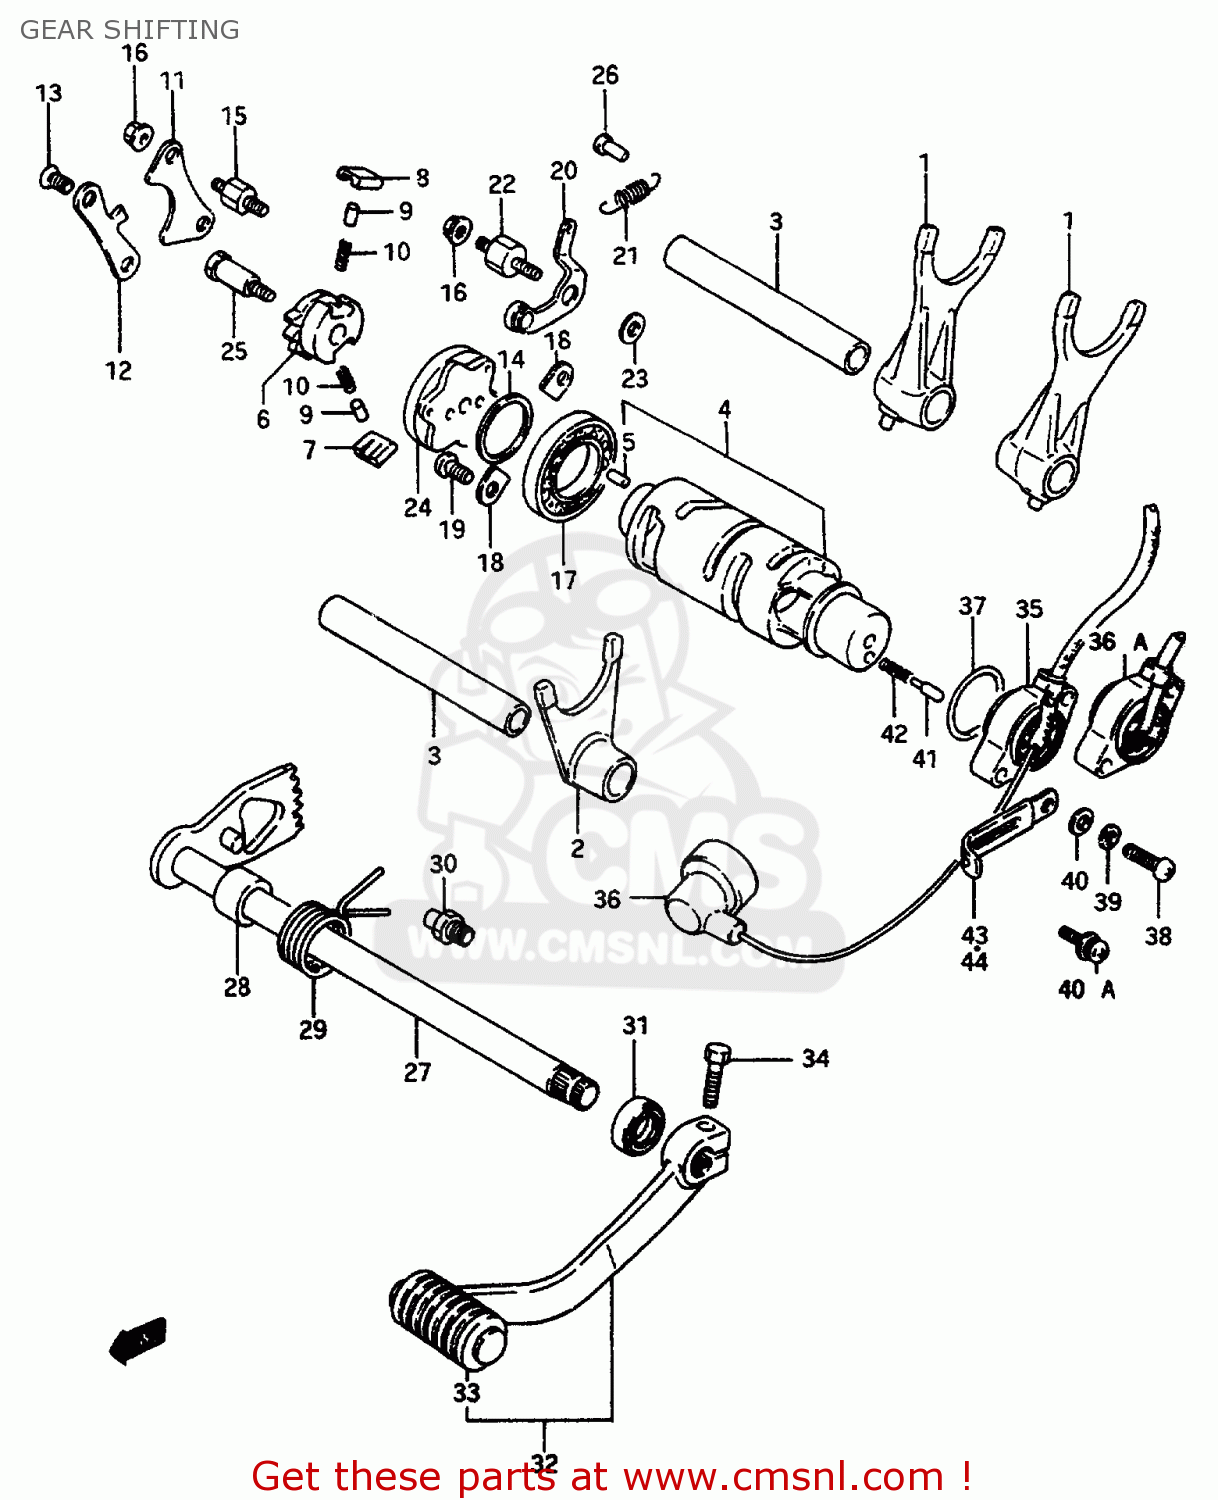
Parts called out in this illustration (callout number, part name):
1	FORK,GEAR SHIFT NO.1
2	FORK,GEAR SHIFT NO.2
3	SHAFT,GEAR SHIFT FORK(L:115)
4	CAM,GEAR SHIFT
5	PIN
6	GEAR,GEARSHIFT CAM DRIVE
7	PAWL,GEAR SHIFT NO.1
8	PAWL,GEAR SHIFT NO.2
9	PIN(5X8)
10	SPRING
11	LIFTER,GEAR SHIFT POLE
12	GUIDE,GEAR SHIFT CAM
13	SCREW
14	WASHER(25X32X3)
15	BOSS,SHIFT PAWL LIFTER
16	NUT
17	BEARING
18	RETAINER
19	SCREW
20	STOPPER,GEAR SHIFT CAM
21	SPRING
22	SUPPORT,CAM STOPPER ARM
23	WASHER
24	PLATE,GEAR SHIFT CAM
25	PIN,SHIFT CAM DRIVEN GEAR
26	RIVET
27	SHAFT,GEAR SHIFT
28	SPACER(12X20X15.3)
29	SPRING
30	STOPPER,GEAR SHIFT CAM
31	OIL SEAL
32	LEVER ASSY,GEAR SHIFT
33	RUBBER,GEAR SHIFT PEDAL
34	BOLT
35	BASE,NEUTRAL SWH TERMINAL
36	CAP,OIL PRESSURE SWITCH
36A	BASE ASSY,GEAR SHIFT TERMINAL
37	O RING(D:2.4,ID:26.2)
38	SCREW
39	WASHER,LOCK
40	WASHER
40A	SCREW
41	PIN(5X15.5)
42	SPRING
43	CLAMP(L:45)
44	CLAMP
